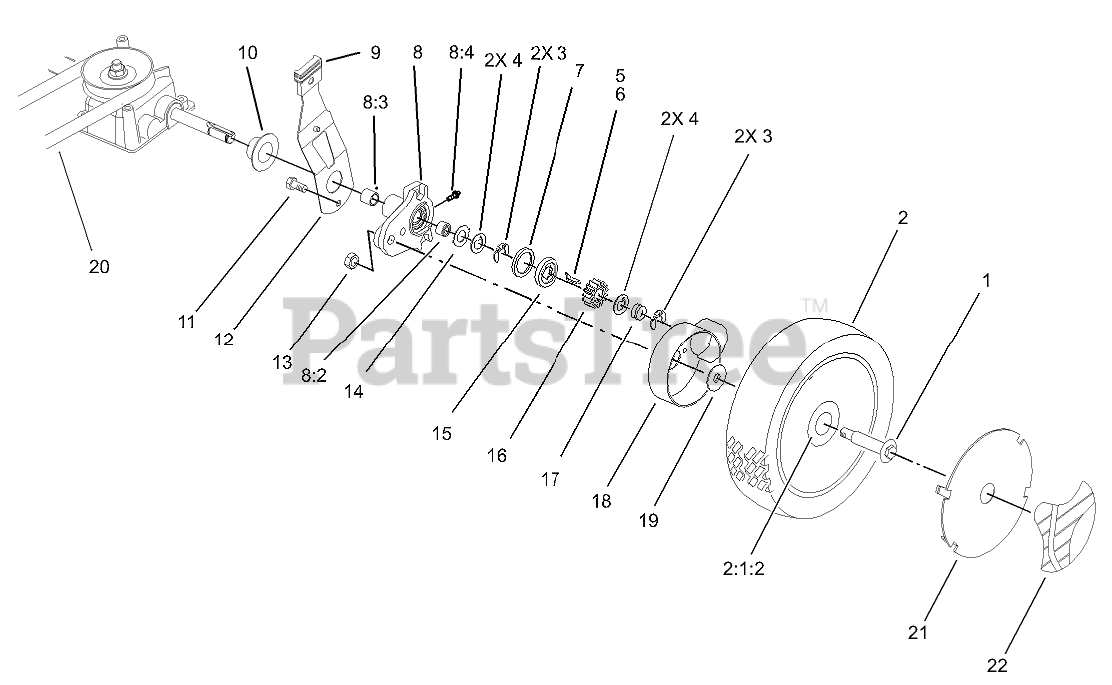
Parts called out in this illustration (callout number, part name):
1	BOLT-SHOULDER
2	WHEEL ASM
2:1	Wheel ASM
2:1:2	BUSHING
3	RING-CLIP, LOCKING
4	WASHER-THRUST, KEYED
5	KEY-ROCKING, RH
6	KEY-ROCKING, LH
7	RING-FRICTION
8	PIVOT ARM ASM
8:2	BUSHING
8:3	BUSHING
8:4	FITTING-GREASE
9	KNOB-ARM
10	CAP-END
11	SCREW-HWH
12	SPRING ARM ASM
14	WASHER-ARM, PIVOT
15	WASHER-CLUTCH
16	GEAR-PINION
17	SPRING-COMPRESSION
18	COVER-WHEEL
19	SPACER-COVER, WHEEL
20	BELT-V
21	COVER-WHEEL
22	LABEL-WHEEL, SMART
